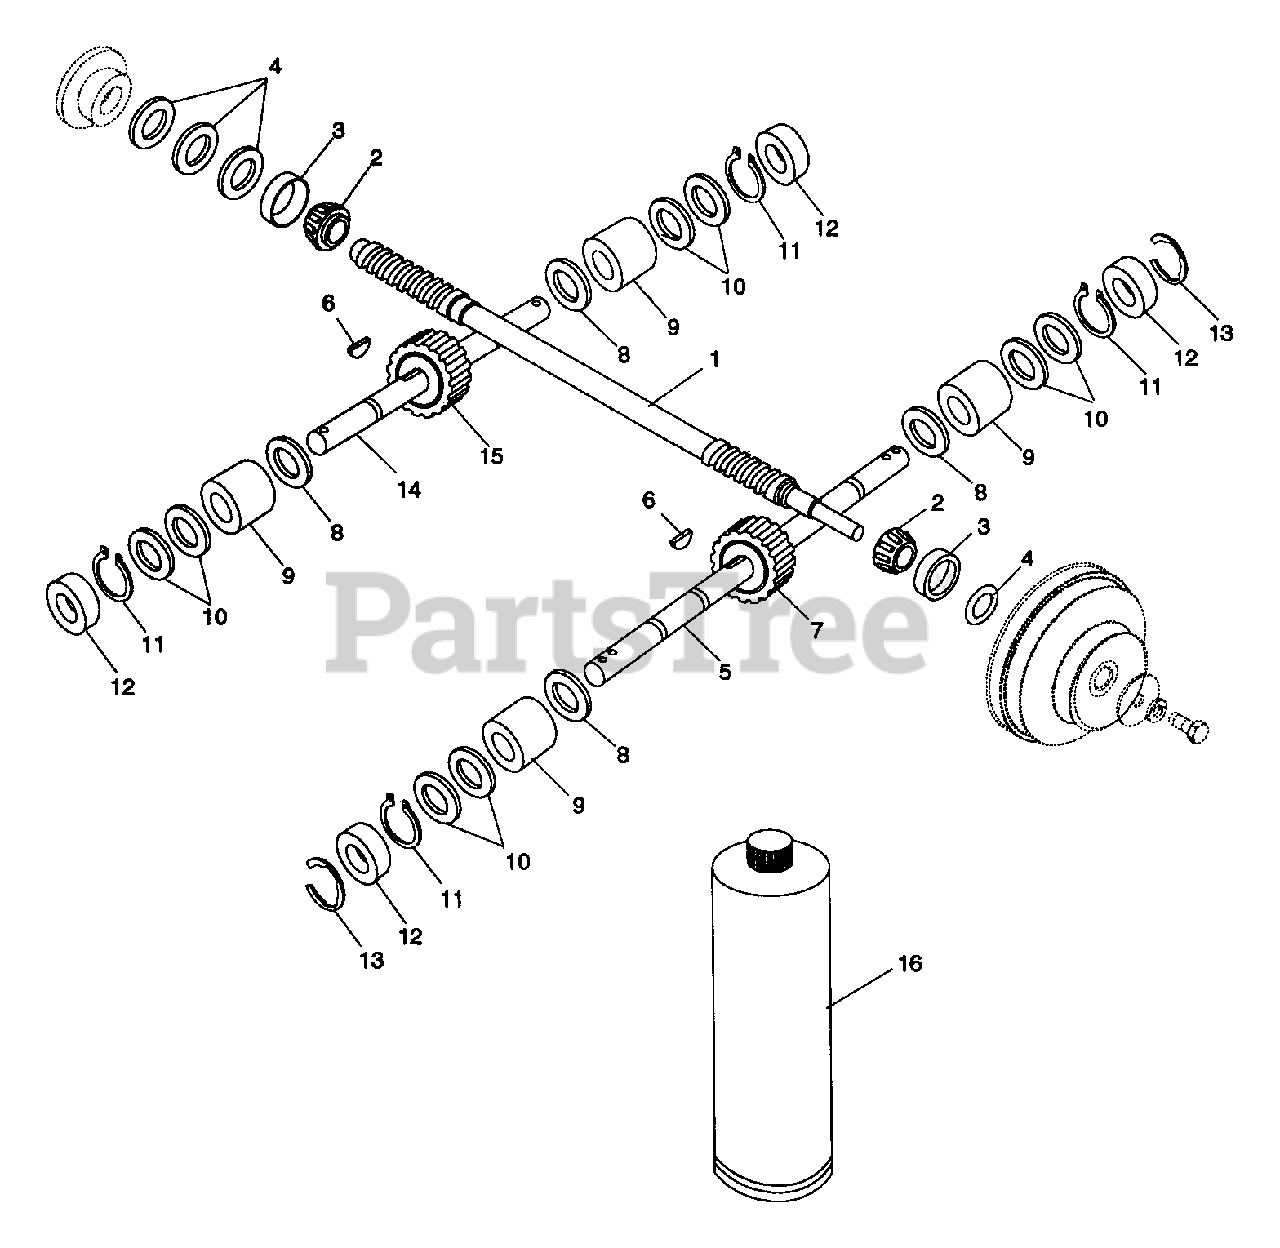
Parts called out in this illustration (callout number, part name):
1	MAIN DRIVE SHAFT
2	BRG-CONE .750X.61
3	BRG-CUP 1.781X.475
4	SHIM SET, REAR CAP
5	WHEEL SHAFT
6	KEY-WDRF .25X1.00X.438 SAE15
7	WORMGEAR, WHEEL SHAFT
8	SPACER (.062)
9	BUSHING
10	SHIM (.062)
10	SHIM (.030)
10	SHIM (.015)
10	SHIM (.010)
11	RG-RTNG .822X1.500X.050 TYP E
12	OIL SEAL, TILLER SHAFT
13	RETAINER, INTERNAL SNAP RING
14	TILLER SHAFT
15	WORMGEAR, TILLER SHAFT
16	ARIENS 16 OZ.BOTTLE OF L2 LUBE
